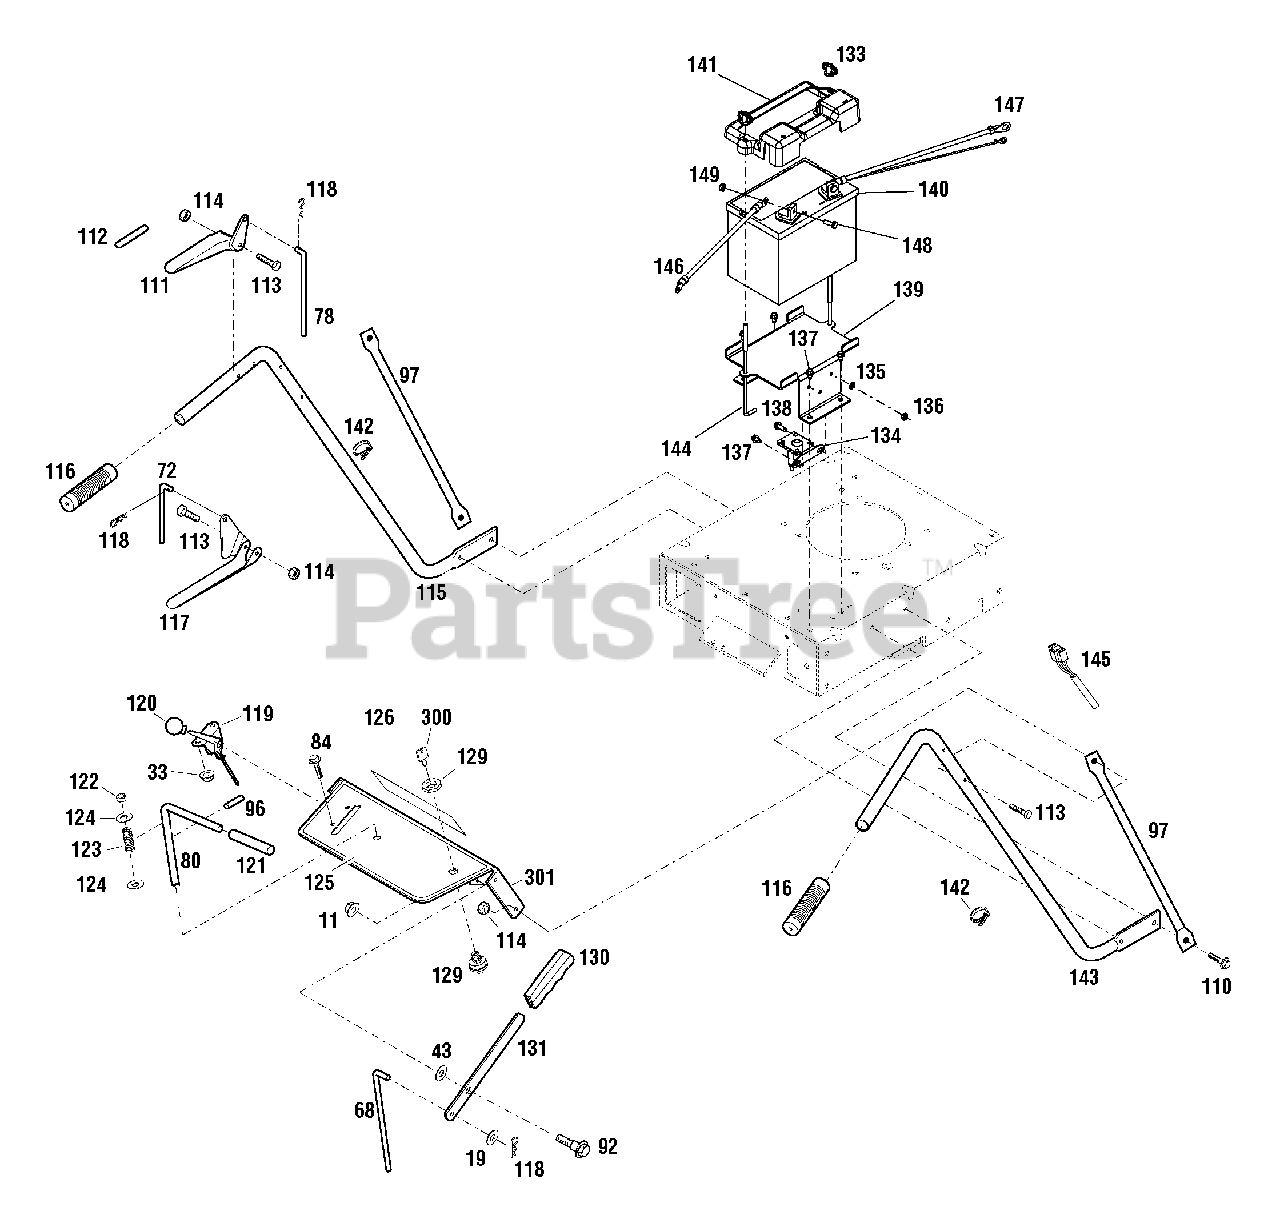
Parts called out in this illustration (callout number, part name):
11	Flange Locknut, 3/8-16
19	Flat Washer, 5/16
33	Flange Locknut, 1/4-20
43	Flat Washer, 1/2
68	Upper Blade Rod
72	Upper Transmission Rod
78	Upper Brake Rod
80	Shift Rod
84	Flange Lock Screw, 1/4-20 x 1/2
92	Shoulder Bolt
96	Roll Pin, 1/4 x 2-1/4
97	Brace, Handlebar
110	Flange Lock Screw, 5/16 x 3/4
111	Control Handle
112	Operator Presence Control Decal
113	Screw, 1/4-20 x 1-3/4, Grade 8
114	Locknut, 1/4-20
115	Left Handlebar
116	Handle Grip
117	Control Handle
118	Hair Pin, 5/64
119	Throttle Control
120	Knob
121	Handle Grip
122	Nylon Bushing
123	Compression Spring
124	Flat Washer, 1/2
125	Warning Decal
126	Logo Decal
129	Ignition Switch w/ Key
130	Handle Grip
131	Mower Engage Lever
133	Wing Nut, 1/4-20
134	Solenoid
135	External Lock Washer, 1/4
136	Jam Nut, 1/4-20
137	Self-tapping Screw, 1/4-20 x 1/2
138	Self-tapping Screw, 1/4-20 x 3/4
141	Battery Cover
142	Plastic Tie
144	Battery Hold-down Rod
145	Wiring Harness
146	Red Wire, 12"
147	Black Wire, 14"
148	Hex Screw, 1/4-20 x .75
149	Hex Sems Nut, 1/4-20
300	Ignition Key
301	Console Assembly
